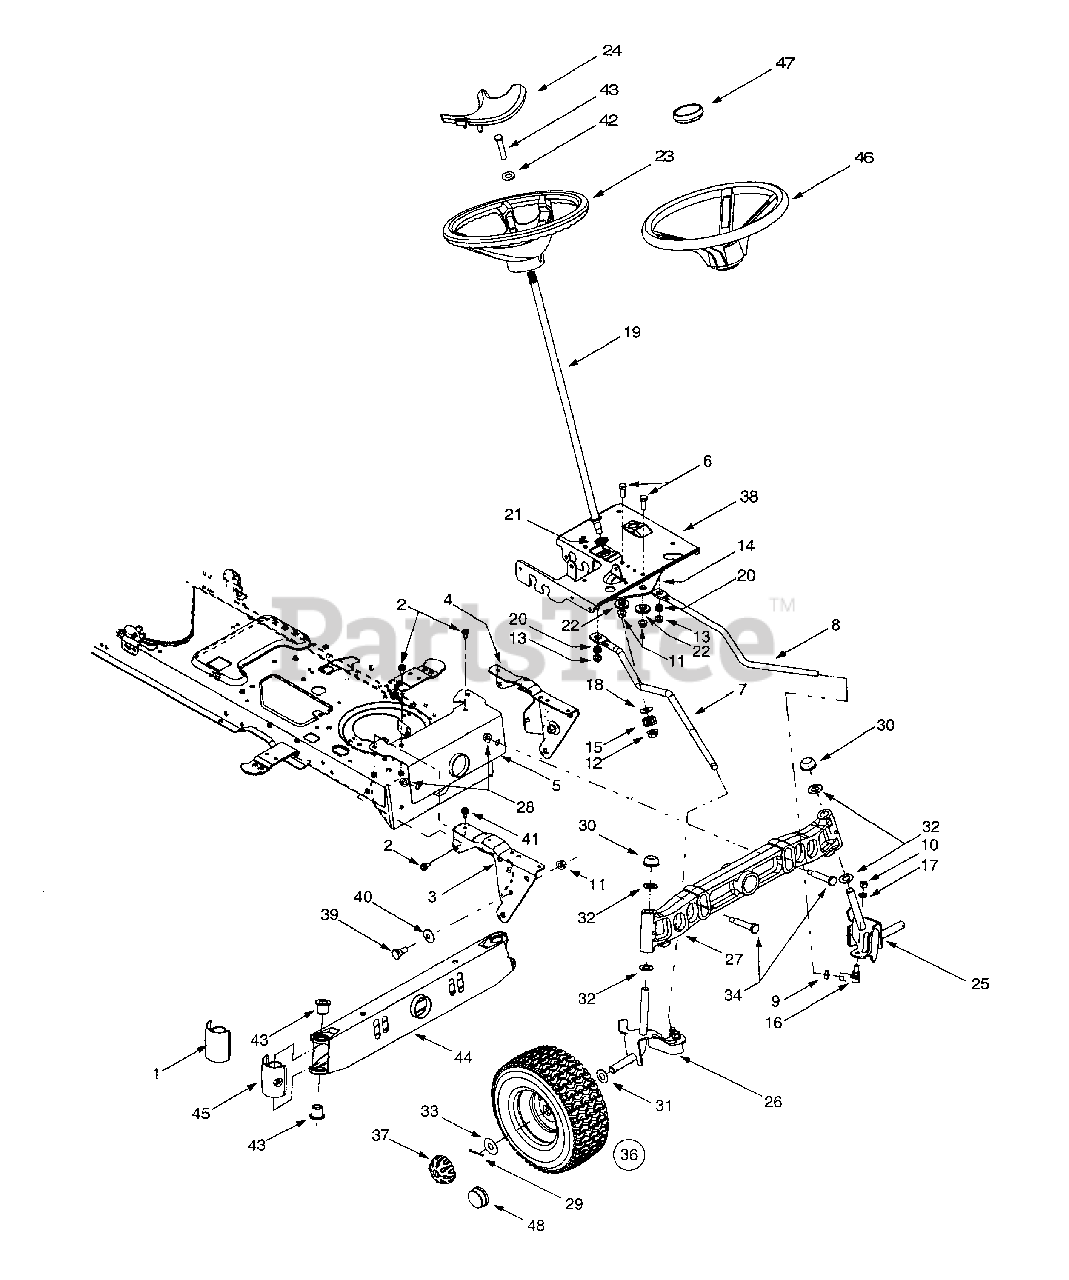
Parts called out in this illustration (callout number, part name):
1	Pivot Bar End Cap w/o Fitting
2	Self-tapping Screw, 16-18 x .625
6	Hex Cap Screw, 3/8-16 x 1 (Grade 5)
7	RH Drag Link
8	LH Drag Link
9	Jam Nut, 7/16-20 (Grade 2)
10	Hex Nut, 3/8-24 (Grade 2)
11	Flange Lock Nut, 3/8-16
12	Flange Lock Nut, 7/16-20
13	Flange Lock Nut, 5/16-18
14	Steering Gear, 11/90 Ratio
15	Steering Pinion Gear
16	Ball Joint, 7/16-20
17	Lock Washer, 3/8
18	Flat Washer, .51 x 1.12 x .06
19	Steering Shaft, .625 OD x 24.4
20	Plastic Bushing, .38 ID
21	Hex Flange Bearing, 5/8
22	Shoulder Spacer, .38 ID
23	Deluxe Steering Wheel
24	Steering Wheel Cap, w/ Icon
25	LH Axle Assembly, .75 Diameter
26	RH Axle Assembly, .75 Diameter
27	Cast Iron Pivot Bar w/ Fittings, .75
28	Flange Lock Nut, 3/8-16
29	Cotter Pin
30	Push Cap, .625
31	Flat Washer, .64 x 1.0 x .12
32	Flat Washer, .78 x 1.59 x .06
33	Flat Washer, .635 x 1.589 x .06
34	Shoulder Screw, .5 x 2.2, 3/8-16
37	Deluxe Hub Cap
39	Shoulder Screw, 3/8-16
40	Bell Washer, .39 x 1.13 x .062
41	Self-tapping Screw, 5/16-18 x .75
42	Bell Washer, .34 x .872
43	Flange Bearing, .760 ID x .937 OD
45	Pivot Bar End Cap w/ Fitting
46	Standard Steering Wheel, 13.25
47	Steering Wheel Cap, Round
48	Standard Hub Cap
